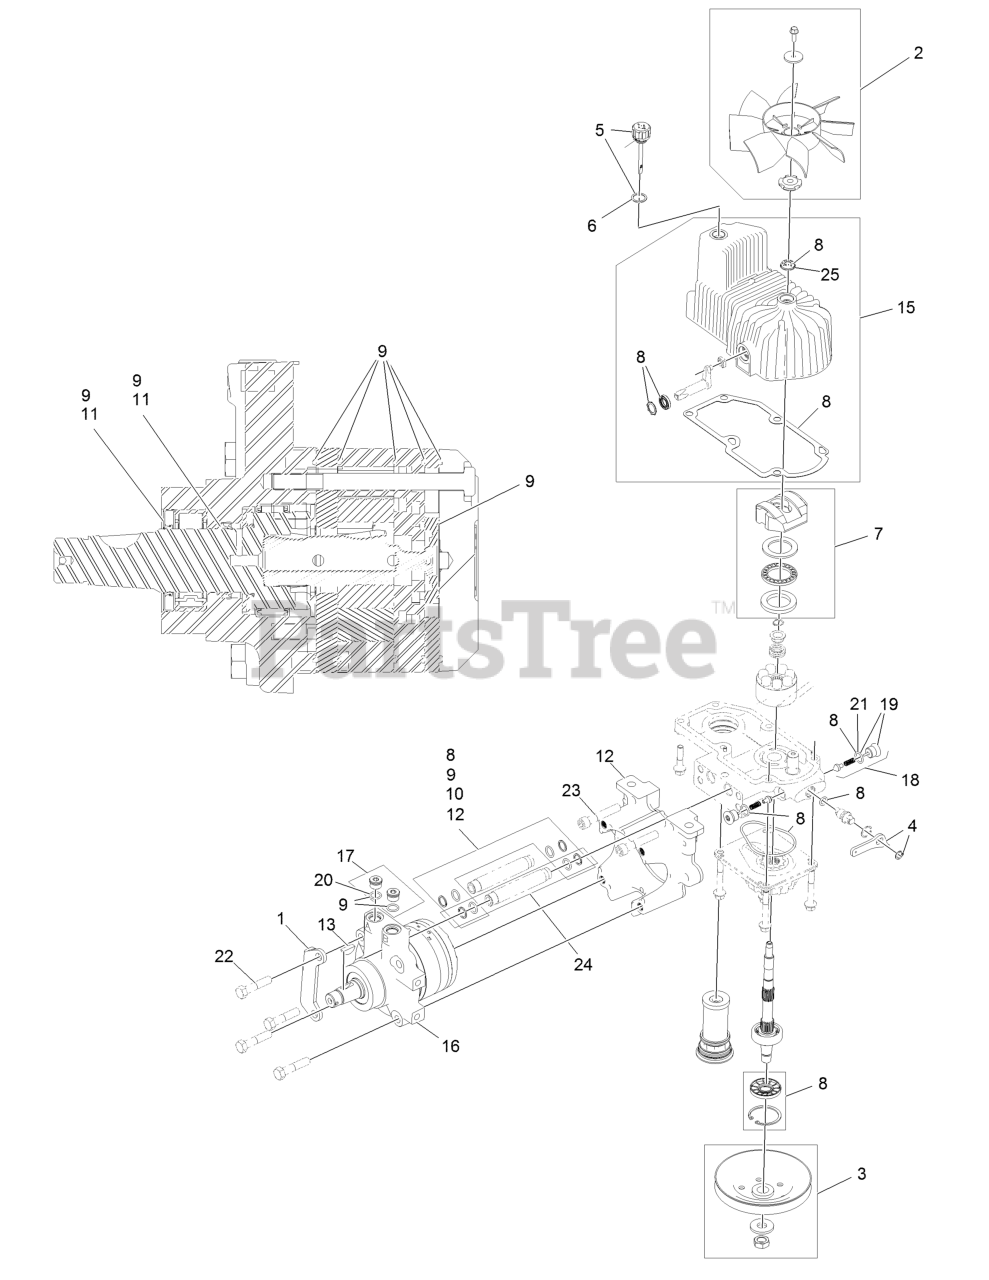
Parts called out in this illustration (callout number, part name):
1	Mount-Shoe, Horse
2	Fan Kit
3	Pulley Kit
4	Handle-Bypass Valve, Hydro
5	Dipstick-Hydro W/Gasket
6	Gasket-Dipstick, Hydro
7	Swash Block Kit
8	Pump Seal Kit
9	Motor Seal Kit
10	Tube Seal Kit
11	Output Shaft Seal Kit
12	Nose Cup-Uht
13	Key-Woodruff 5/16 X 1
15	Housing-RH
16	Motor-Hydraulic RH 240Cc
17	Magnetic Plugs Service Kit
18	Check Valve ASM
19	Plug-Check (W/O-Ring)
21	O-Ring-Check Valve
22	Screw-HH 1/2-20 X 2 1/4
23	Screw-HSH 1/2-20 X 2 3/4
24	Hydraulic Tube Kit
25	Seal-Fan Drive
99	Flow Test Kit
99	Puller-Pulley
